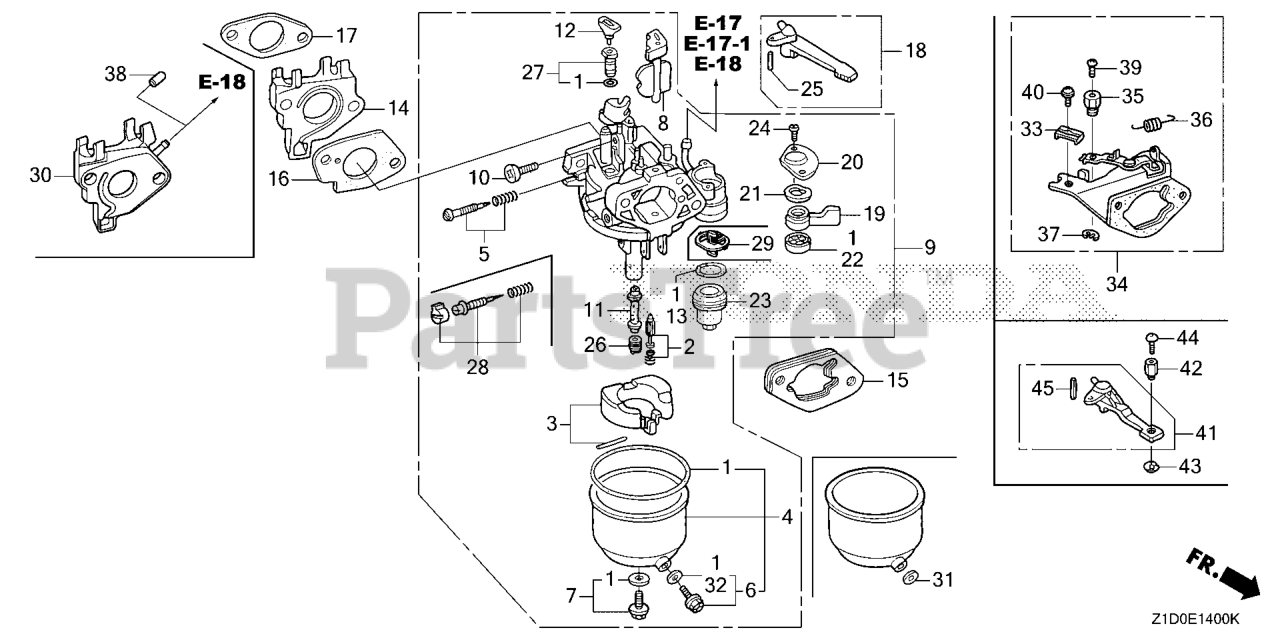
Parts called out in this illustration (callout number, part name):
1	GASKET SET (INCLUDE 16173-001-004) (INCLUDES 16173-001-004)
2	VALVE SET, FLOAT
3	FLOAT SET (CARBURETOR NO.)
4	CHAMBER SET, FLOAT
6	SCREW SET, DRAIN
7	SCREW SET (CARBURETOR NO.)
8	CHOKE SET
9	CARBURETOR ASSY. (BE70U A)
10	SCREW, THROTTLE STOP
11	NOZZLE, MAIN (CARBURETOR NO.)
12	COLLAR, SET
13	GASKET, FUEL STRAINER CUP
14	INSULATOR, CARBURETOR
15	SPACER, CARBURETOR
16	GASKET, CARBURETOR
17	GASKET, INSULATOR
18	LEVER, CHOKE (STD)
19	LEVER, VALVE
20	PLATE, LEVER SETTING (CARBURETOR NO.)
21	SPRING, PETCOCK LEVER (CARBURETOR NO.)
22	GASKET, VALVE
23	CUP, FUEL STRAINER
24	SCREW, PAN (3X6)
25	PIN, SPRING (2X12)
26	JET, MAIN (#82)
26	JET, MAIN (#85) Use up to Engine SN BE81B B.
26	JET, MAIN (#88) Use up to Engine SN BE81B B.
27	JET SET, PILOT (#35)
29	FILTER, CUP (CARBURETOR NO.)
32	WASHER, PLAIN (6.2X10.7 DRAIN) (CARBURETOR NO.)
